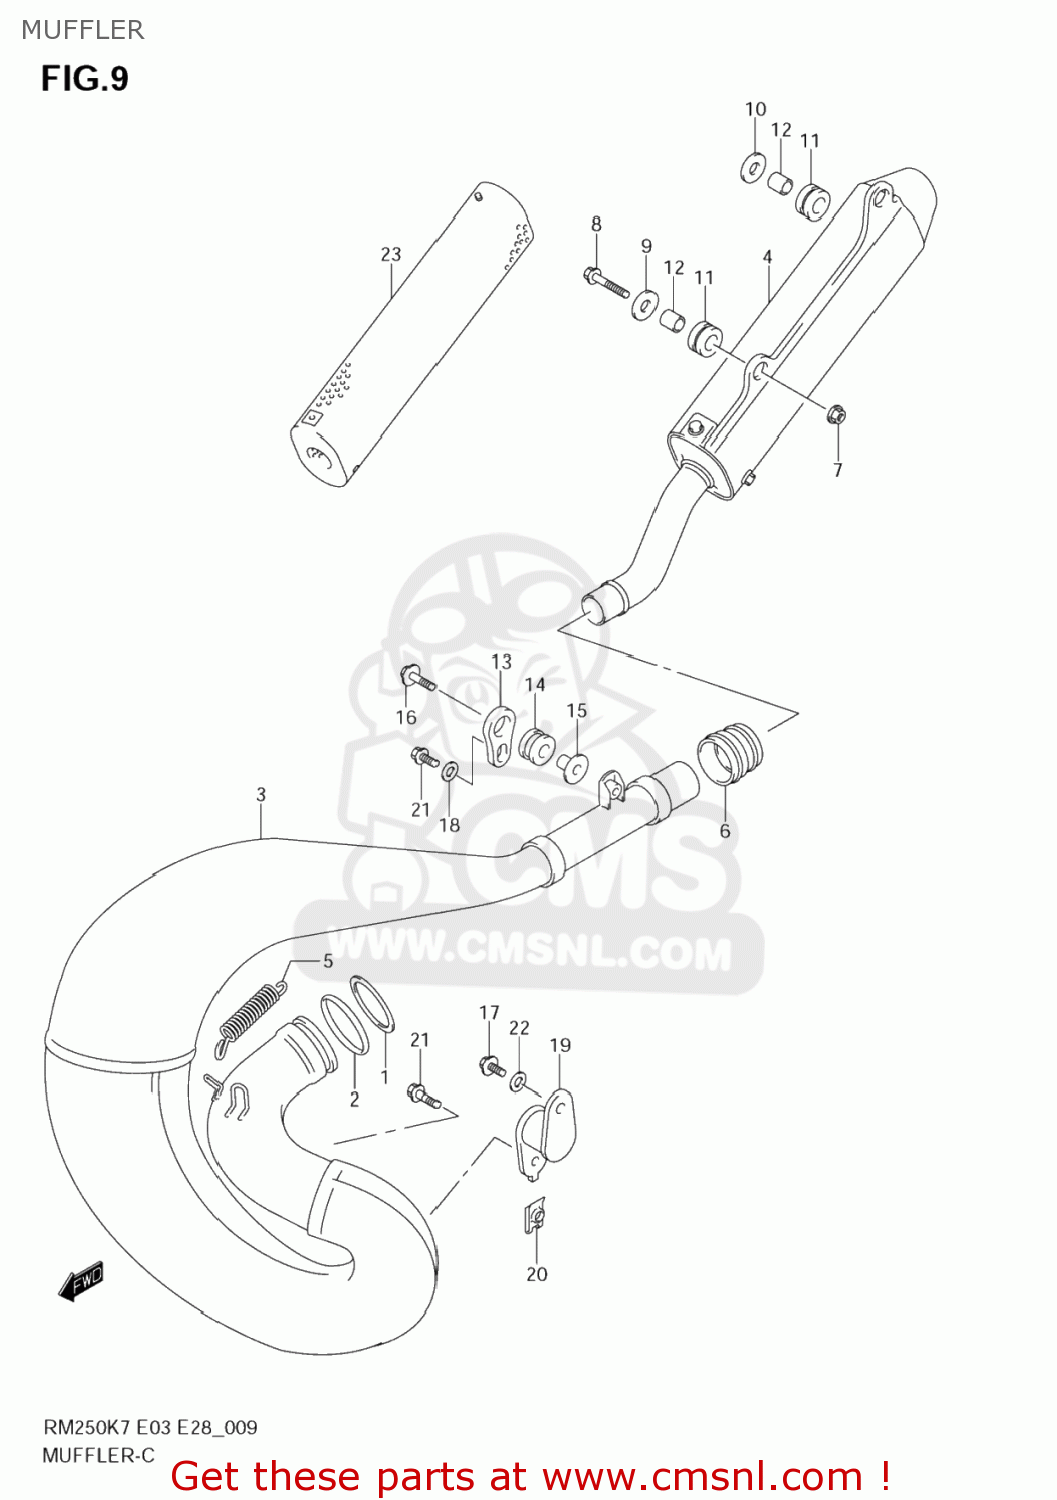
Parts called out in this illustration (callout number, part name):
1	WASHER,EXHAUST PIPE
2	O RING,EXHAUST PIPE
3	BODY,MUFFLER
4	BODY,MUFFLER 2ND
5	SPRING
6	CONNECTOR,MUFFLER
7	NUT
8	BOLT(6X30)
9	WASHER(6.5X24X1.2)
10	WASHER(6.5X24X1.2)
11	CUSHION
12	SPACER(6.5X11.5X12)
13	PLATE,MUFFLER MTG
14	CUSHION,MUFFLER
15	SPACER,MUF MTG
16	BOLT(6X25)
17	BOLT(6X12)
18	WASHER(6.5X18X1.6)
19	DAMPER,MUFFLER
20	NUT
21	BOLT(6X16)
22	WASHER(6.5X18X1.6)
23	SILENCER,MUFFLER
